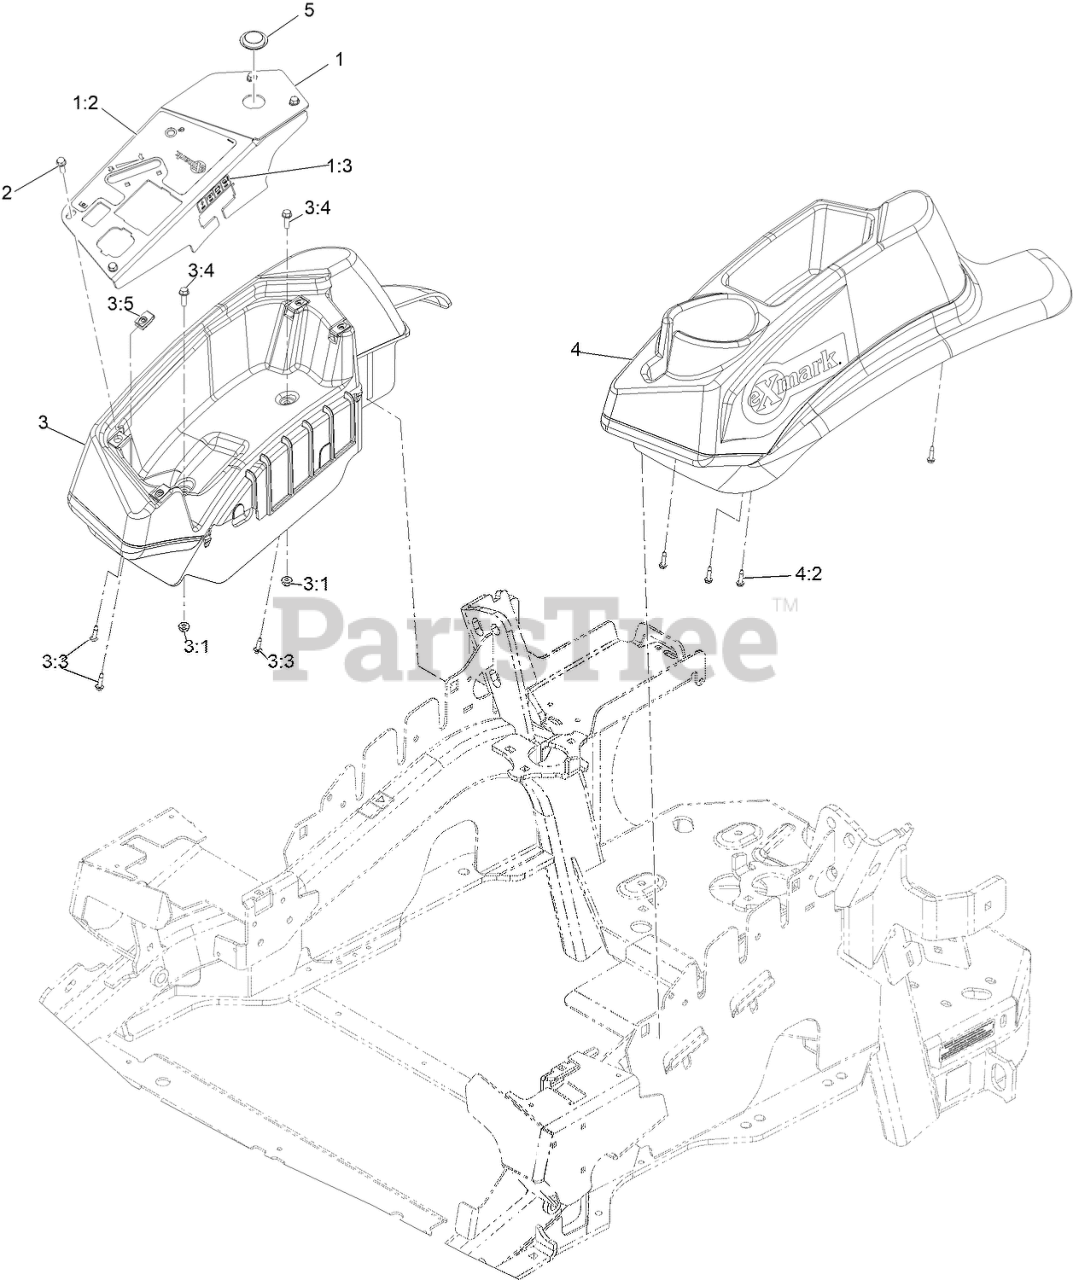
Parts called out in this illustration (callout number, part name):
1	ASM,CONTROL PANEL W/DECAL
1:2	DECAL-CONTROL PANEL EFI
1:3	DECAL-FUSES
2	SCREW-HWH
3	CONSOLE,RH NARROW ASM
3:3	SCREW,THD FORM,HWH
3:4	SCREW-HWH
4	CONSOLE.LH NARROW ASM
4:2	SCREW,THD FORM,HWH
5	PLUG-PLASTIC
